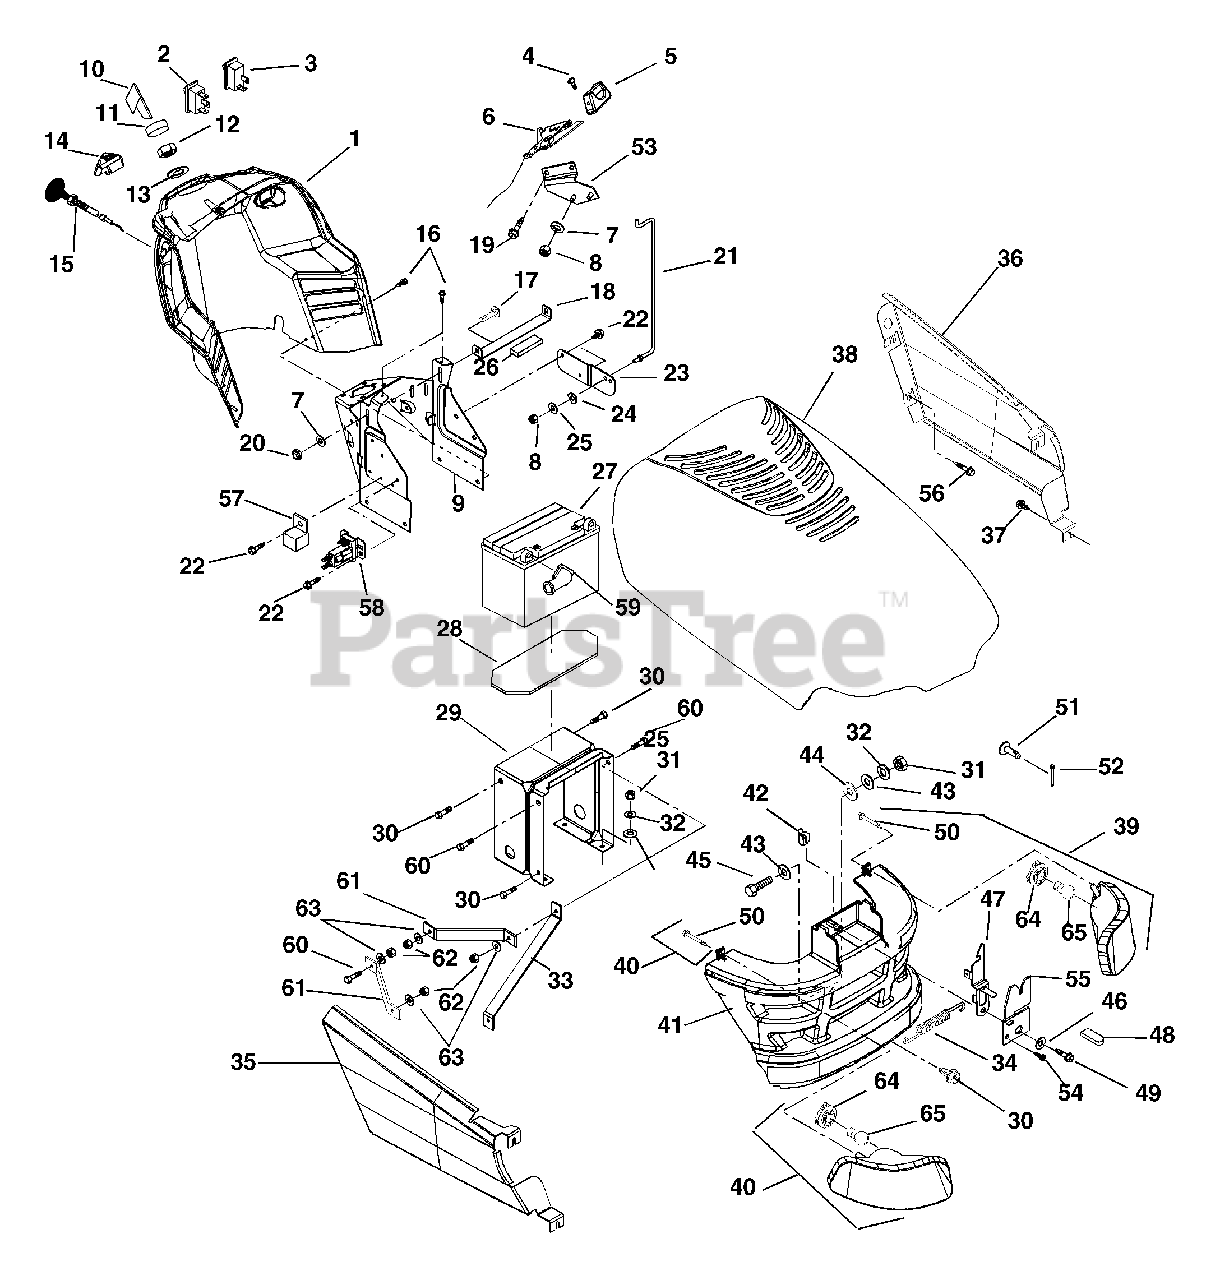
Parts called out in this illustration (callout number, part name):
1	DASH-VENTED
2	SWITCH - CRUISE
3	SWITCH - LIGHT
4	SCR-SET 10-24X.38 UNC-3A
5	KNOB, THROTTLE
6	CABLE, THROTTLE
7	WSHR-FL-STL .323X.625X.062 YWZ
8	@NUT-LK-CTR .25-20 YWZC
9	SUPPORT, DASH TOP
10	KEY -W/CAP
11	CAP - IGNITION SWITCH
12	NUT- PANEL .562-24 GRECO
13	WSHR-LK-INT .625X.045 YWZC
14	PTO KNOB / SHAFT ASSY.
15	CHOKE CABLE
16	SCR-TAP 10-24X.484 HWH TR
17	@BLT-RDHDSQNK .31-18X.75 G5YZ
18	HOLDD0WN, BATTERY
19	@SCR-TAP .25-20X.37 HWH YWZ TR
20	@NUT-LK-NYL .312-18 YWZC
21	ROD - HOOD PROP
22	@SCR-TAP 10-24X.375 HWH YZ TR
23	MOUNT - PROP ROD
24	WAVE WASHER .390X.655X.110
25	@WSHR-FL-STL.312X.734X.065 YWZ
26	PAD, FOAM
27	BATTERY W/ TUBE
28	RUBBER PAD
29	SUPPORT-DASH BASE
30	SCR-TAP .312-18X.50 HWH TR BL
31	@NUT-HEX .31-18 YWZC
32	WSHR-LK .312X.097 HVY YWZC
34	SG-TENS .035X.45X2.75 WLD 3.5
35	PANEL, R.H
36	PANEL, L.H
37	SCR-TAP 12-16X.500 HI-LOTPHBL
38	HOOD WITH DECALS
39	HEADLIGHT- LH
40	HEADLIGHT- RH
42	CLIP-HARNESS TINNERMAN
43	WSHR-FL-STL .328X1.0X.094 YWZC
44	WSHR-FL-NYL .390X1.000X.062
45	@BLT-HEX .31-18X1.00 GR5 YWZC
46	WSHR-FL-STL .281X1.250X.048 BL
47	HOOD LATCH
48	GRIP .062 X .375 X 1.000 RE
49	SCR-TAP 12-24X.50 HWH TR BLACK
50	SCR-TAP 10-24X.75 HWH TR YWZC
51	PIN, CLEVIS .243/.248X1.50 YWZ
52	@PIN-CTR .09X.75 EXTPRSQCT YWZ
53	BRACE, THROTTLE CONTROL
54	SCR-TAP 10-12X.50 CRPH PL A BL
55	LOCATOR, HOOD
56	SCR-TAP 10-16X.62 SLPH AB YWZC
57	RELAY
58	SOLENOID
59	INSULATOR
60	@BLT-HEX .31-18X.75 GR5 YWZC
61	BRACKET-STEERING ASSEMBLY
62	@NUT-LK-NYL .312-18 YWZC
63	@WSHR-FL-STL.344X.688X.065YWZC
64	LAMP SOCKET
65	HEADLIGHT BULB, 1156
